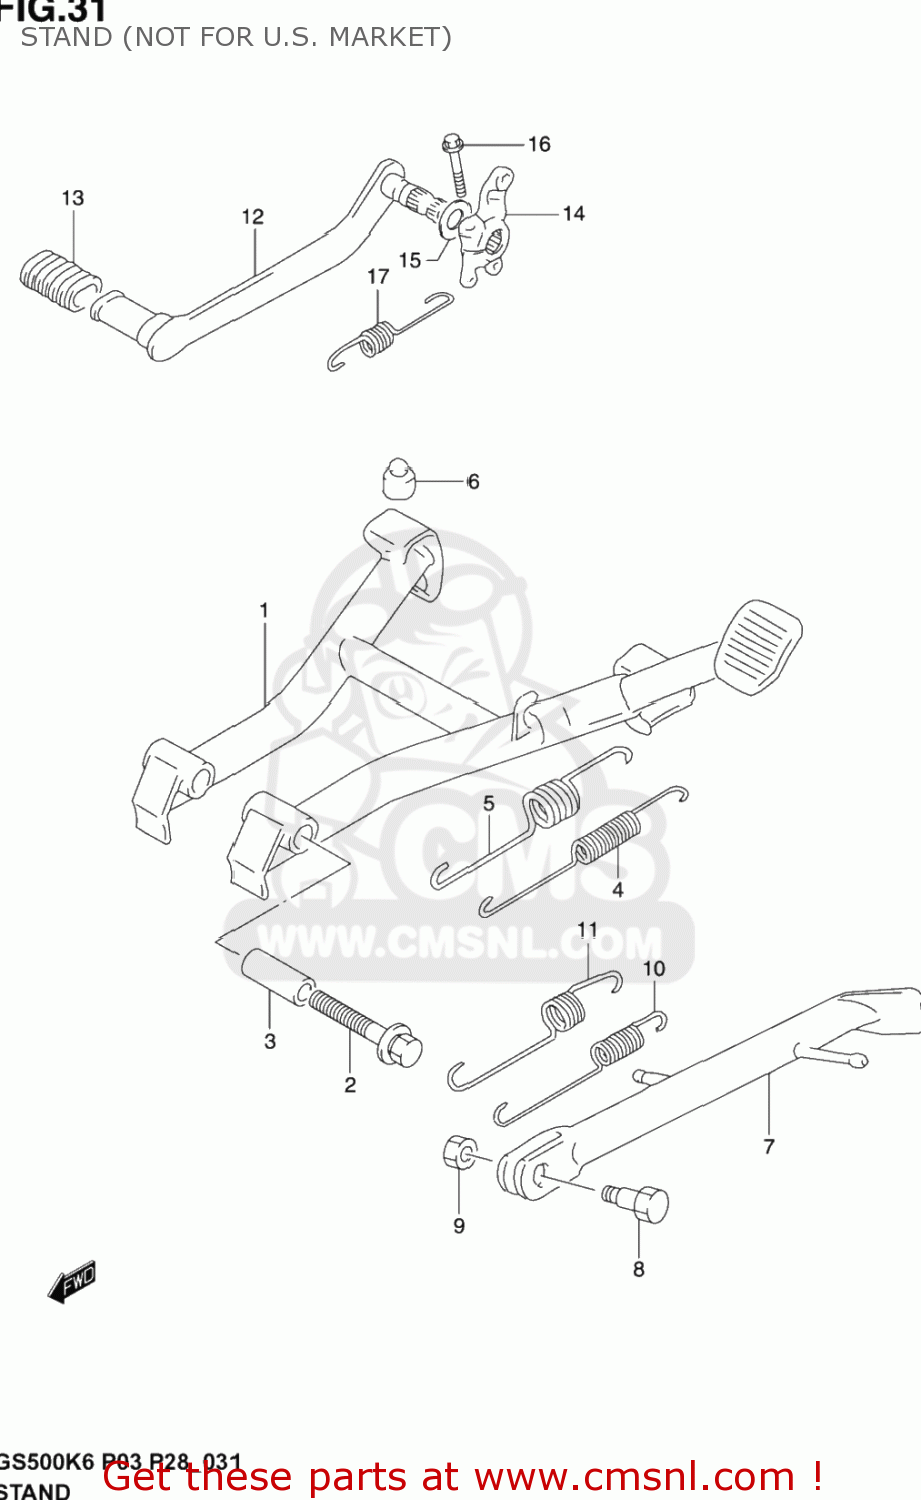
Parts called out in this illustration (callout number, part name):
1	STAND,CTR
2	BOLT
3	SPACER(10X16X38.8)
4	SPRING
5	SPRING OUTER
6	CUSHION
7	STAND,PROP(BLACK)
8	BOLT(10X34)
9	NUT
10	SPRING
11	SPRING
12	PEDAL,BRAKE
13	RUBBER,PEDAL
14	ARM, BRAKE ROD
15	WASHER
16	BOLT
17	SPRING
